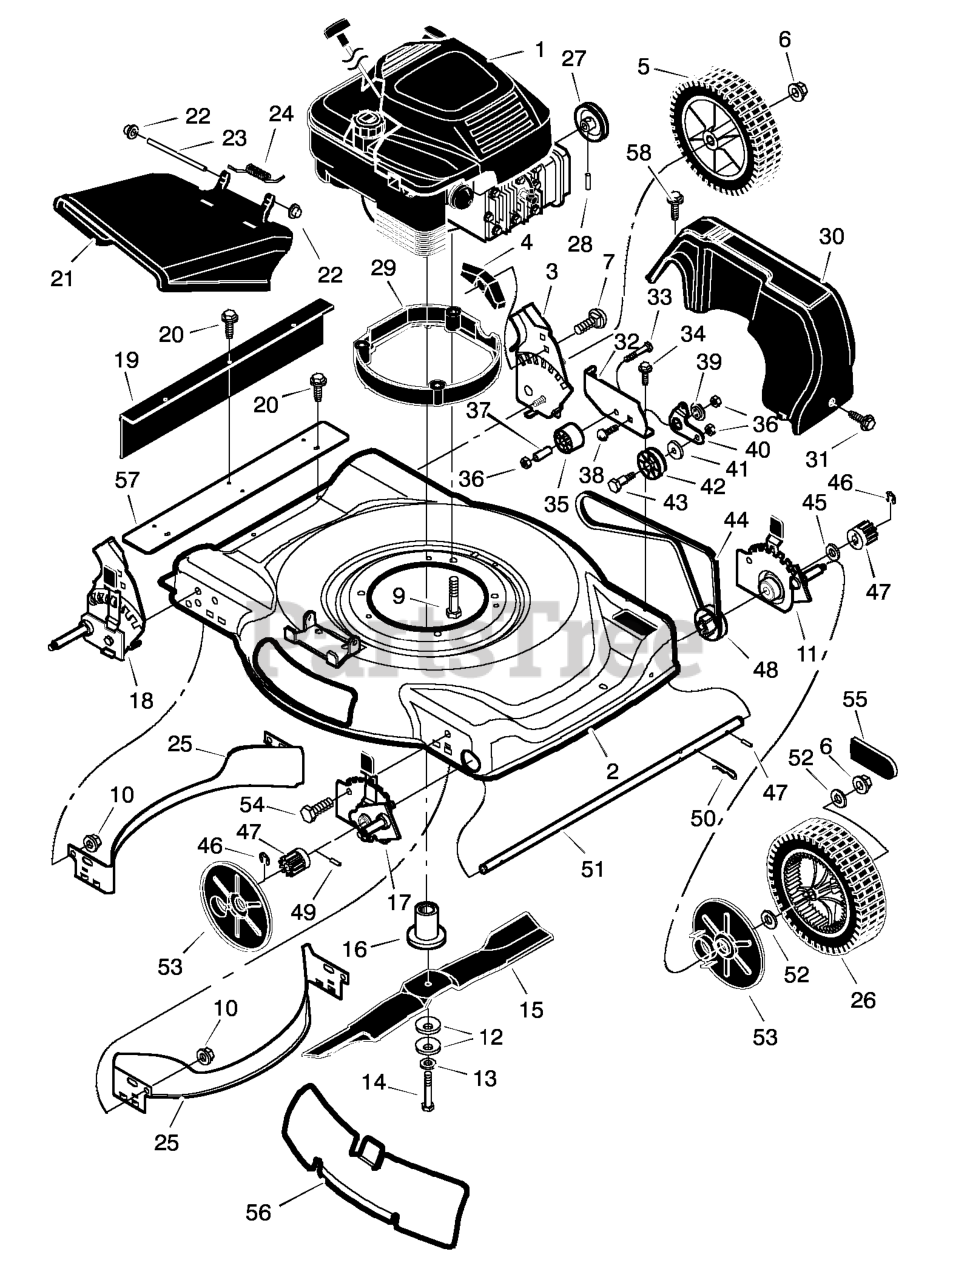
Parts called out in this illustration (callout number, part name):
1	Engine
2	Housing
3	Height Adjuster, Left Rear
5	Wheel and Tire, Rear
6	Locknut, Flange
7	Bolt, Carriage
9	Bolt, Engine
10	Nut
11	Height Adjuster, Left Front
12	Washer, Belleville
14	Bolt, Hex
16	Adapter, Blade
17	Height Adjuster, Right Front
18	Height Adjuster, Right Rear
19	Guard, Rear
21	Deflector, Chute
22	Push- On Cap
23	Pin, Pivot
26	Wheel and Tire, Drive
28	Pin, Spring
29	Base, Engine
30	Cover, Belt
32	Bracket, Idler Support
36	Locknut
37	Bearing
38	Bolt, Carriage
40	Arm, Idler
42	Pulley, Idler
43	Bolt, Shoulder
46	Ring, Retainer
47	Gear, Pinion
49	Pin, Drive
50	Pin, Hair
52	Washer
53	Cover, Dust
54	Bolt
55	Hub Cap
56	Plate, Mulcher
57	Extension, Rear
